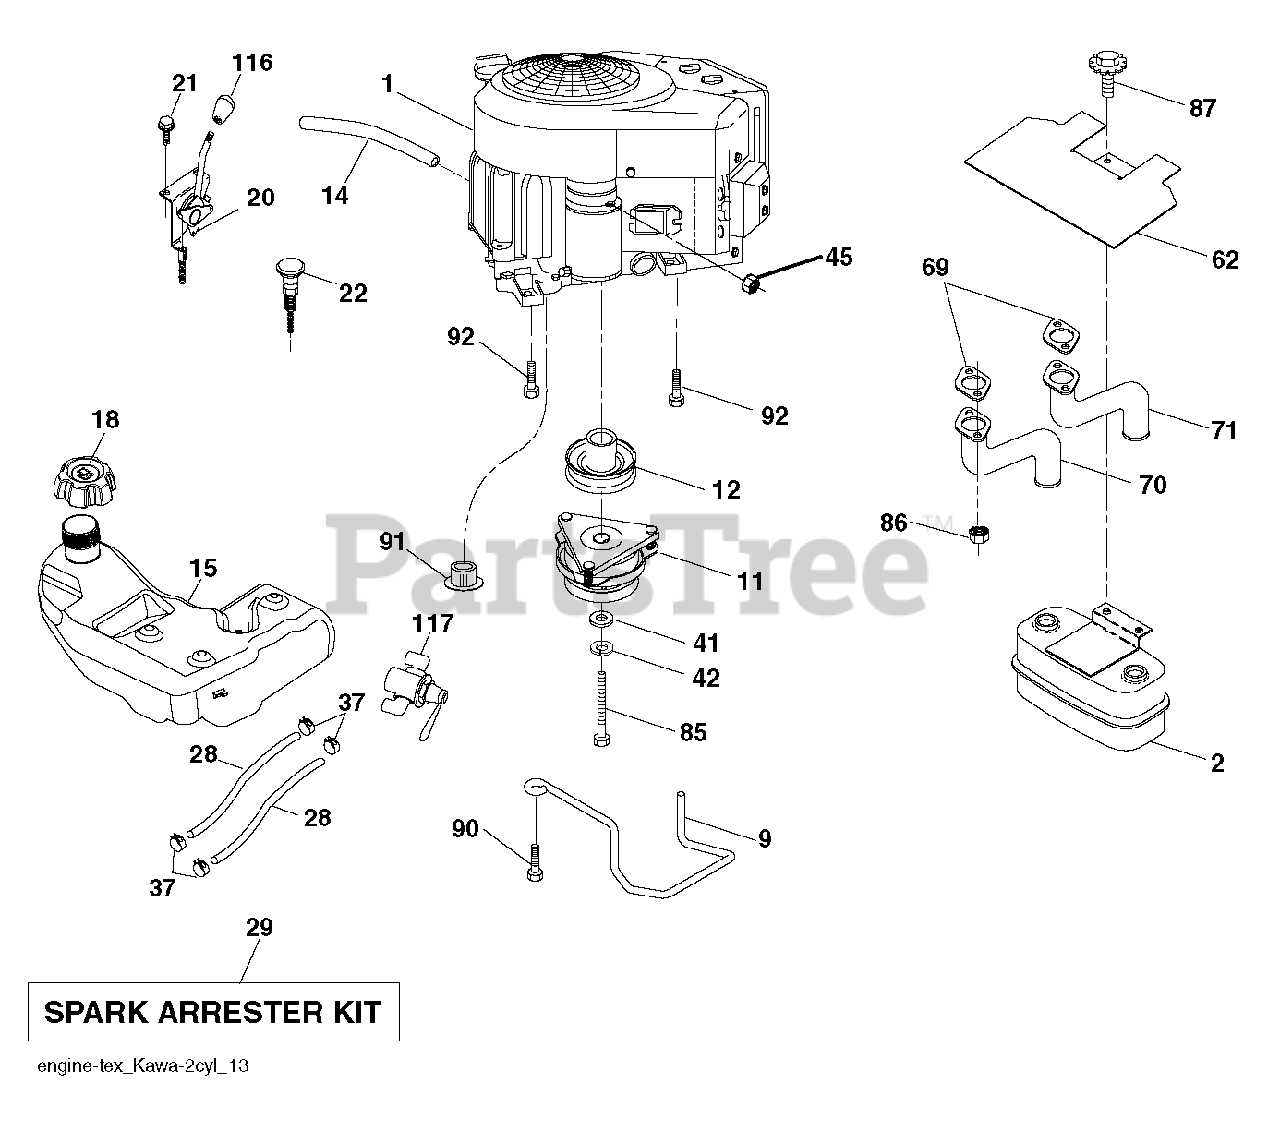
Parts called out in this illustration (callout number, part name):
2	MUFFLER.ASM.TWN.EXTNDED.DFLCTR
9	KEEPER.BELT.ENGINE.4.2
11	CLUTCH.ELECTRIC.LT.48"*
12	PULLEY.ENGINE.TUFFTORQ
14	TUBE, DRAIN OIL ASM.
15	TANK.ASM.4.GAL.CARB.1.PORT.REA
18	CAP.FL.R.3'N/CARB.H.CROWN.498
20	CONTROL.THROTTLE.PRO.
21	SCREW.#10 X 0.750.BOS
22	CONTROL.CHOKE.ERGO.PUSH-IN.BLA
28	LINE.FUEL.64"REAR.EMIS
29	KIT.SPARK ARRESTOR 794945 B&S
37	HOSE CLAMP
42	LOCKWASHER
45	NUT
62	SHIELD.HEAT.MUFFLER
70	TUBE.EXHAUST.LH.FR961/FR730
71	TUBE.EXHAUST.RH.FR961/FR730
85	BOLT HEX 7/16-20X4-1/4"
86	NUT.HEX.FLANGE.TOPLOCK
87	Bolt, 5/16-18 X 1-3/4
90	SCREW 3/8-16X1
91	BUSHING.1.375OD
92	SCREW 3/8-16X1
116	KNOB - SHIFT
117	VALVE FUEL RESERVE
